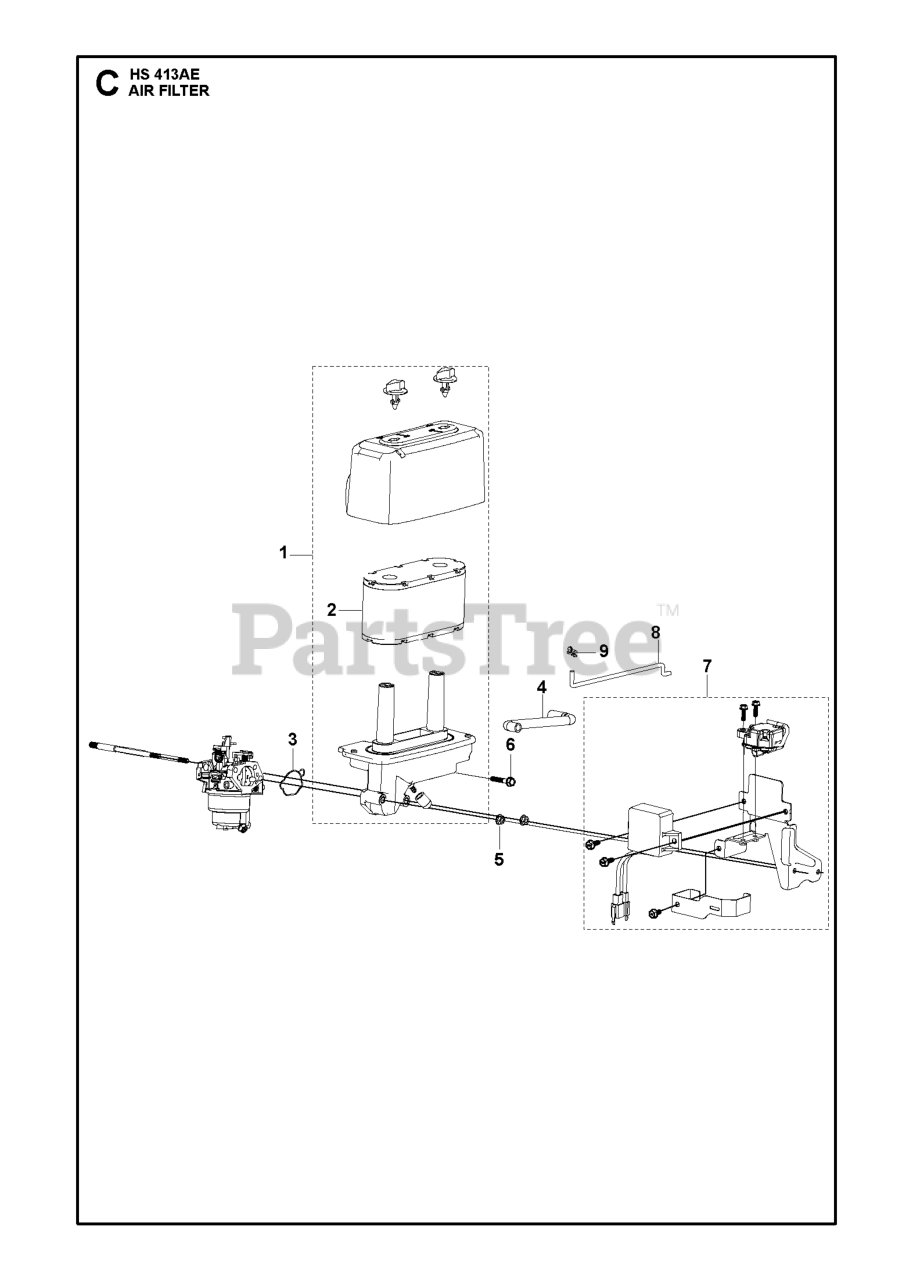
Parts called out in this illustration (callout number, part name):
3	GASKET CARBURETTOR GASKET
5	NUT GB/T 6177.1: M6
6	BOLT GB/T 5789: M6 L=35
